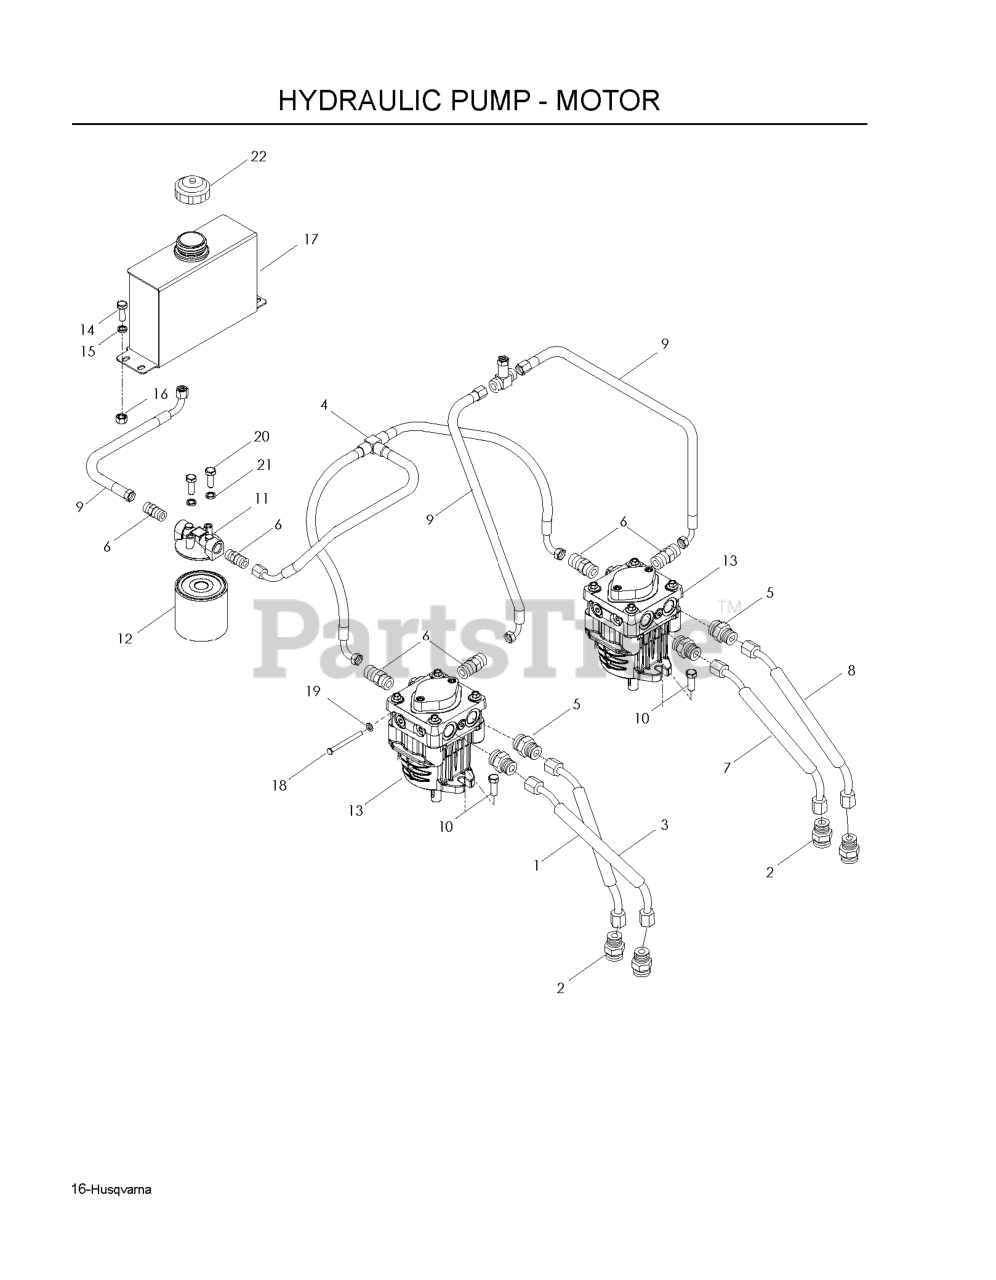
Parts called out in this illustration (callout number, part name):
1	HOSE, RPB-MA LINE
3	HOSE, RPA-MB LINE
4	HOSE, T-ASM SUPPLY
5	FITTING, STRAIGHT F6400-8-8-0
6	FITTING HYDRAULIC
7	HOSE, LPB-MB LINE
8	HOSE, LPA-MA LINE
9	HOSE, RETURN LINE
10	4CS 3/8C X 1 SERRATED HEAD
11	FILTER HEAD
12	HYDRAULIC OIL FILTER
13	HG_PUMP, 10CC W/O FAN OR RTN
14	HCS 1/4C X 3/4 HCS
15	WASHER 1/4 FLAT
16	NUT 1/4C CENTER LOCK
17	OIL TANK BLK
18	CLEVIS PIN
20	HCS 1/4C X 5/8
21	LOCKWASHER 1/4"
22	HYDRAULIC CAP
